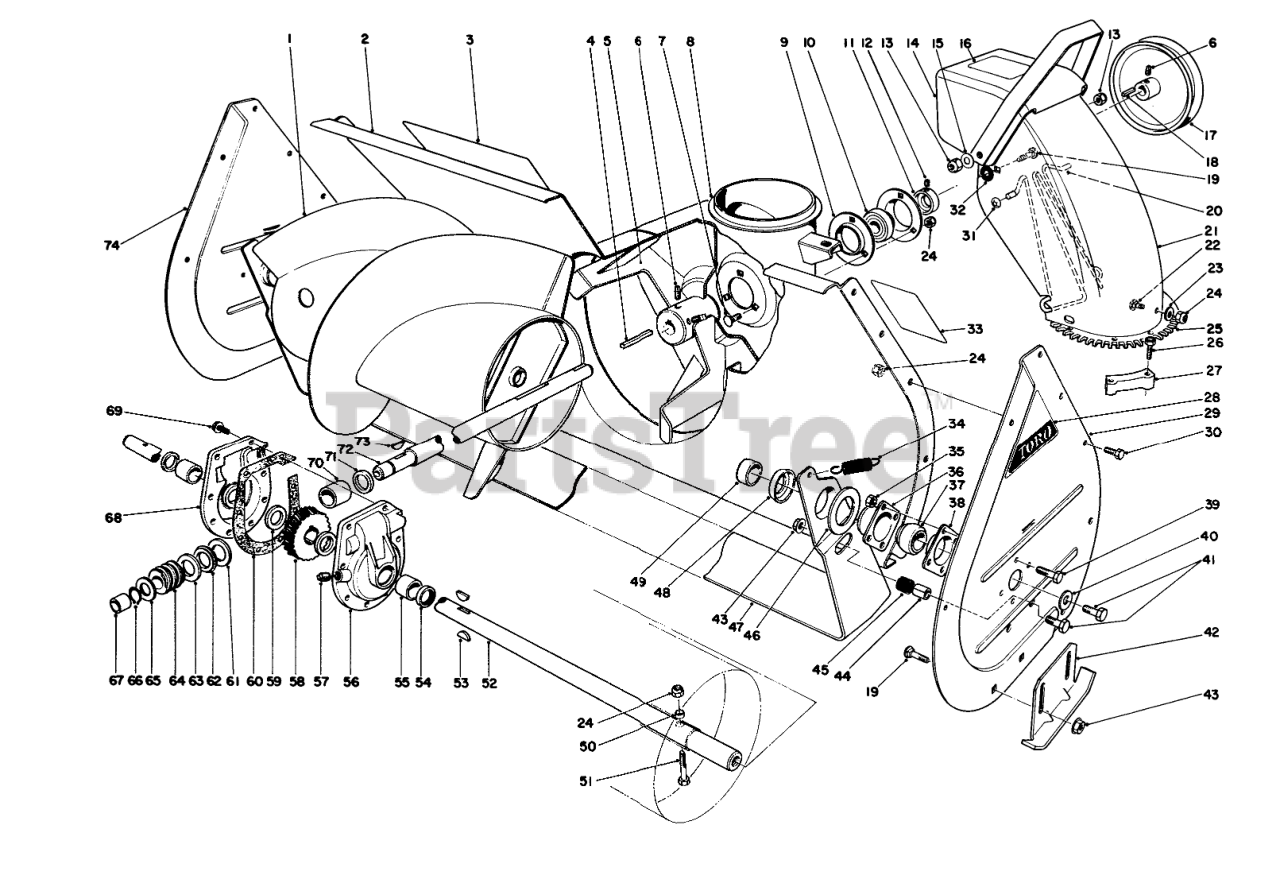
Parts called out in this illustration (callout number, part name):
1	RH AUGER ASM - 32"
2	AUGER HSG WA 32" R
3	AUGER WARNING DECAL
5	IMPELLER ASM
6	SCREW-SET, SQH
7	BOLT-CARR
8	CHUTE RING
9	BRG FLANGE
10	BALL BRG W/COLLAR
11	EXT LOCKING COLLAR
12	SCREW-HSH
13	NUT-LOCK, CONE
14	Deflector (Incl. Ref. #16)
15	WASHER-BELLEVILLE
16	Decal-Danger
17	1/2 X 9.5 DIA PULLEY
18	SQUARE KEY
19	SCREW-CARR
20	CHUTE WIRE
21	Upper Chute
22	SCREW-CARR
23	WASHER-PLAIN
24	NUT-LOCK, NI
25	Screw
26	SCREW-SPECIAL
27	RETAINER-CHUTE
28	AUGER SIDE PLT DECAL
29	LH AUGER SIDE PLT R
30	SCREW-HH
31	NUT-PUSH
32	WASHER-RUBBER
33	DECAL-WARNING, AUGER
34	SPRING-TENSION
35	NUT-LOCK, CONE
36	BEARING-FLANGE, FRONT
37	BEARING
38	BEARING-FLANGE, REAR
39	SCREW-HH
40	WASHER
41	SCREW-HH
42	AUGER SKID WA R
43	NUT-HF
44	SCRAPER STOP SPACER
45	SCRAPER STOP CUSHION
46	SCRAPER BLADE SPACER
47	SCRAPER BLADE 32" R
48	Positioner-Scraper
49	AUGER SPACER
50	SPACER-HUB, AUGER
51	Auger Bolt
52	32 AUGER SHAFT
53	KEY-WOODRUFF
54	SEAL-OIL
55	BUSHING
56	Gear Case L.H. (Incl. Ref. #54-55)
57	PLUG-PIPE, SQH
58	GEAR-WORM, 27T
59	WASHER-THRUST
60	GASKET-CASE, GEAR
61	WASHER-THRUST
62	BEARING-THRUST
63	THRUST-WASHER
65	WASHER-THRUST
66	Ring-Snap
67	BUSHING
68	Gear Case R.H. (Incl. Ref. #54-55)
69	SCREW-TAPTITE
70	BUSHING-SPECIAL
71	RING-QUAD
72	SHAFT-IMPELLER
73	KEY-WOODRUFF
